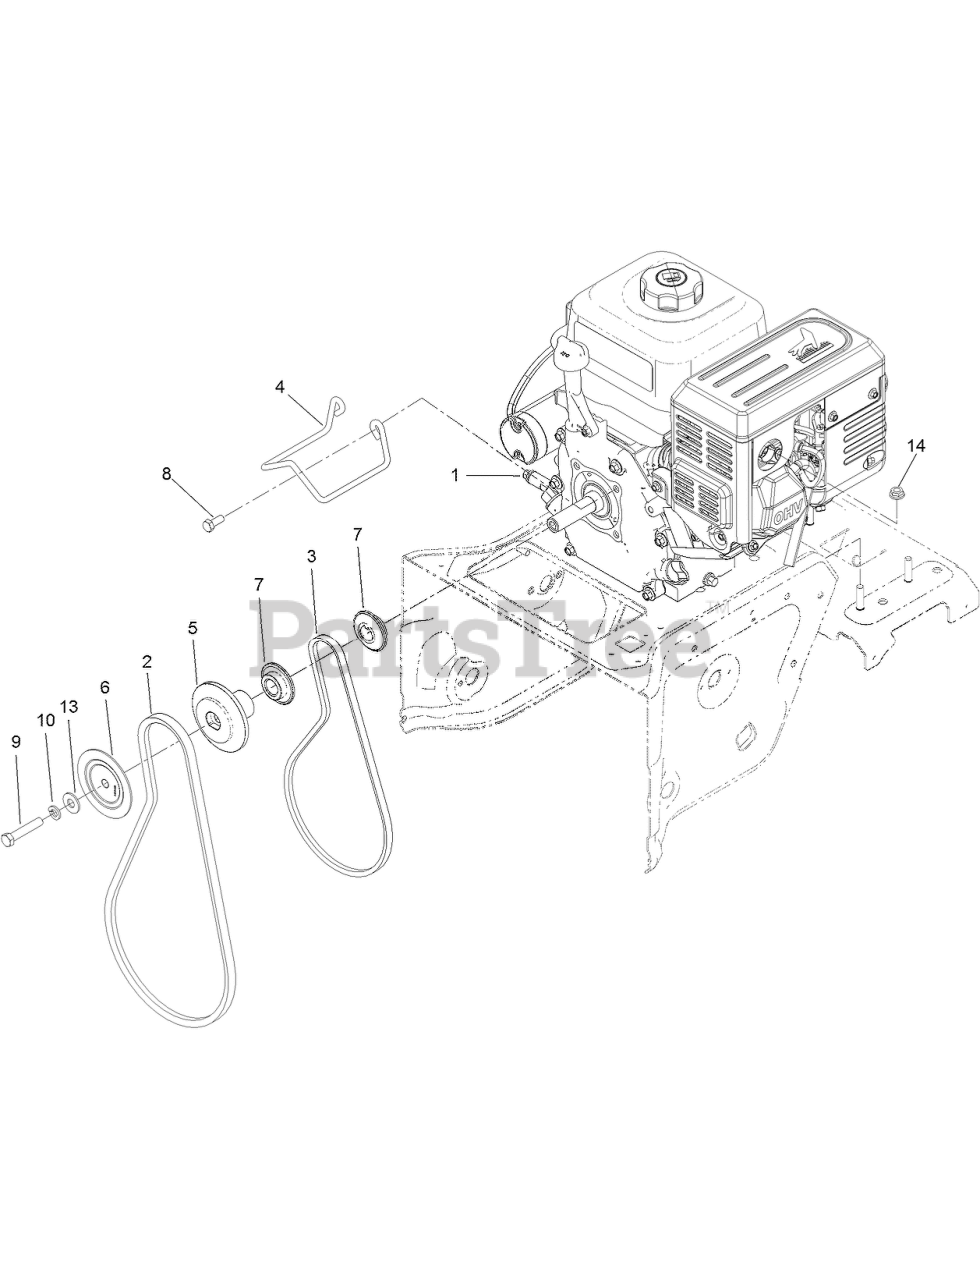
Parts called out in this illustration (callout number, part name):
1	ENGINE-G250FDS-1
2	BELT-V
3	BELT-V
4	GUIDE-BELT
5	PULLEY-AUGER, REAR
6	PULLEY-AUGER, FRONT
7	PULLEY-ENGINE, TRACTION
8	SCREW-HH
9	SCREW-HH
10	WASHER-LOCK
13	WASHER-PLAIN
14	NUT-HF
